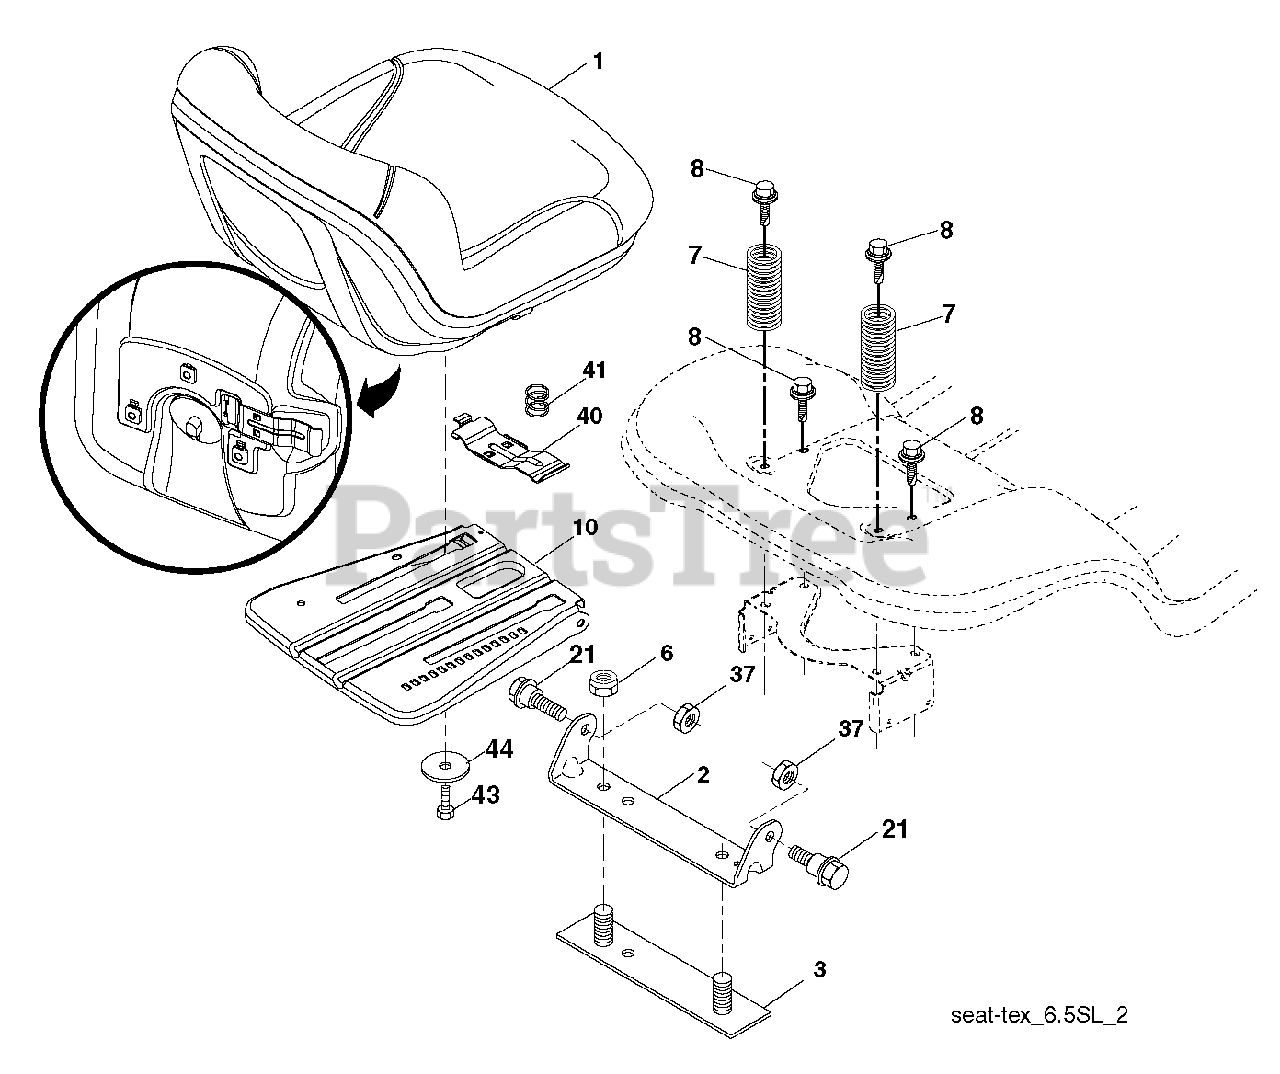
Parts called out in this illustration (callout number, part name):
1	SEAT.TH154.GREY.HUS.ARMREST
2	BRKT.PIVOT.FENDER
3	STRAP
6	NUT
7	SPRING COMPRESSION
8	BOLT, 5/16-18 X 1 3/4
10	PAN.ASM.SEAT.3PT
21	BOLT.SHOULDER.5/16-18
37	NUT.71038.31-18.HEX.NYLOCK
40	HANDLE.SLIDE.SEAT.TEX.BLACK
41	SPRING.LATCH.SEAT.TEX
44	WASHER 13/32 X 2-3/8 X 12GA
